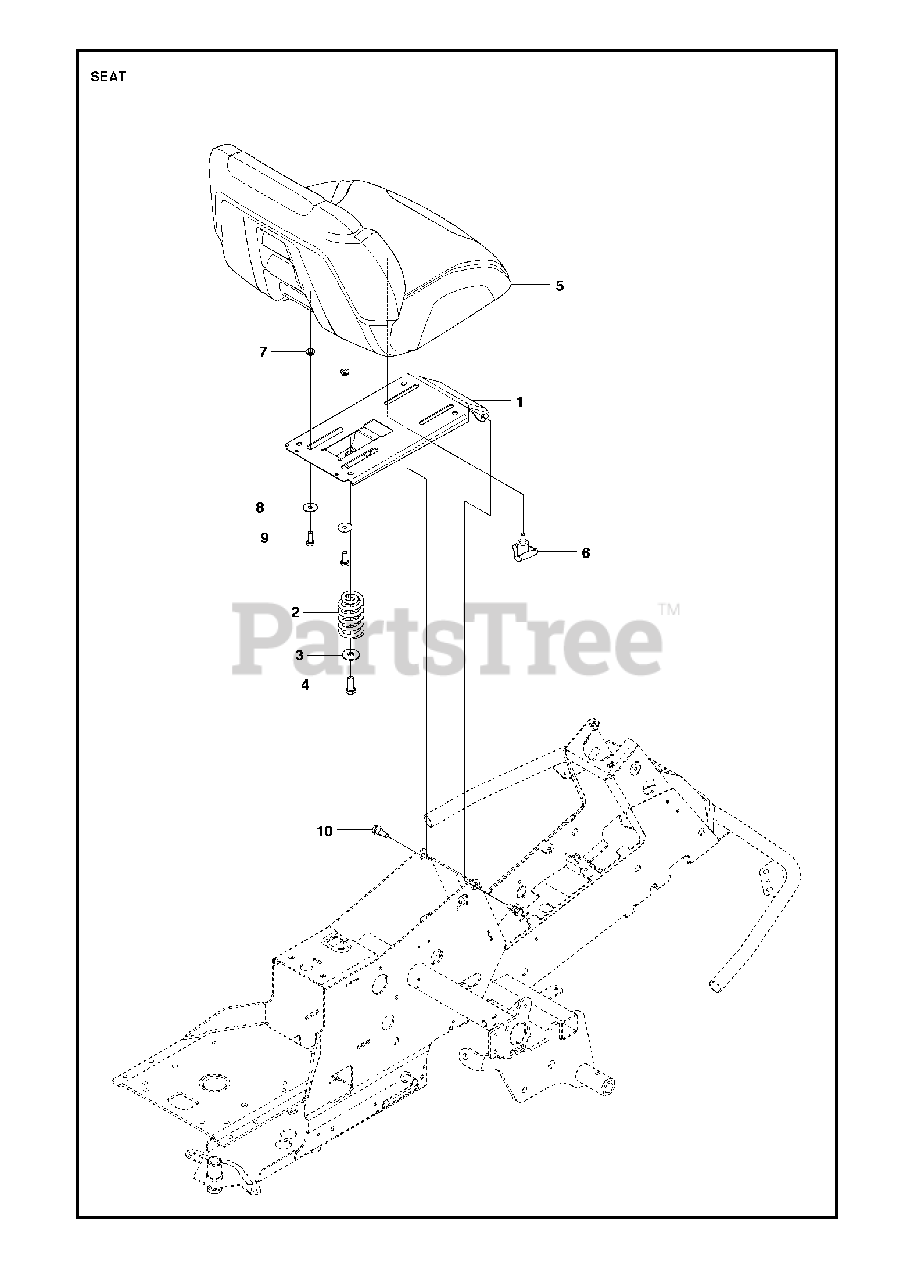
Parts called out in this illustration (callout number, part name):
1	SEAT BRACKET 300 ASSY GREY
2	SEAT SPRING
4	Screw, M10 X 25
5	SEAT HUSQVARNA LOW BACK
